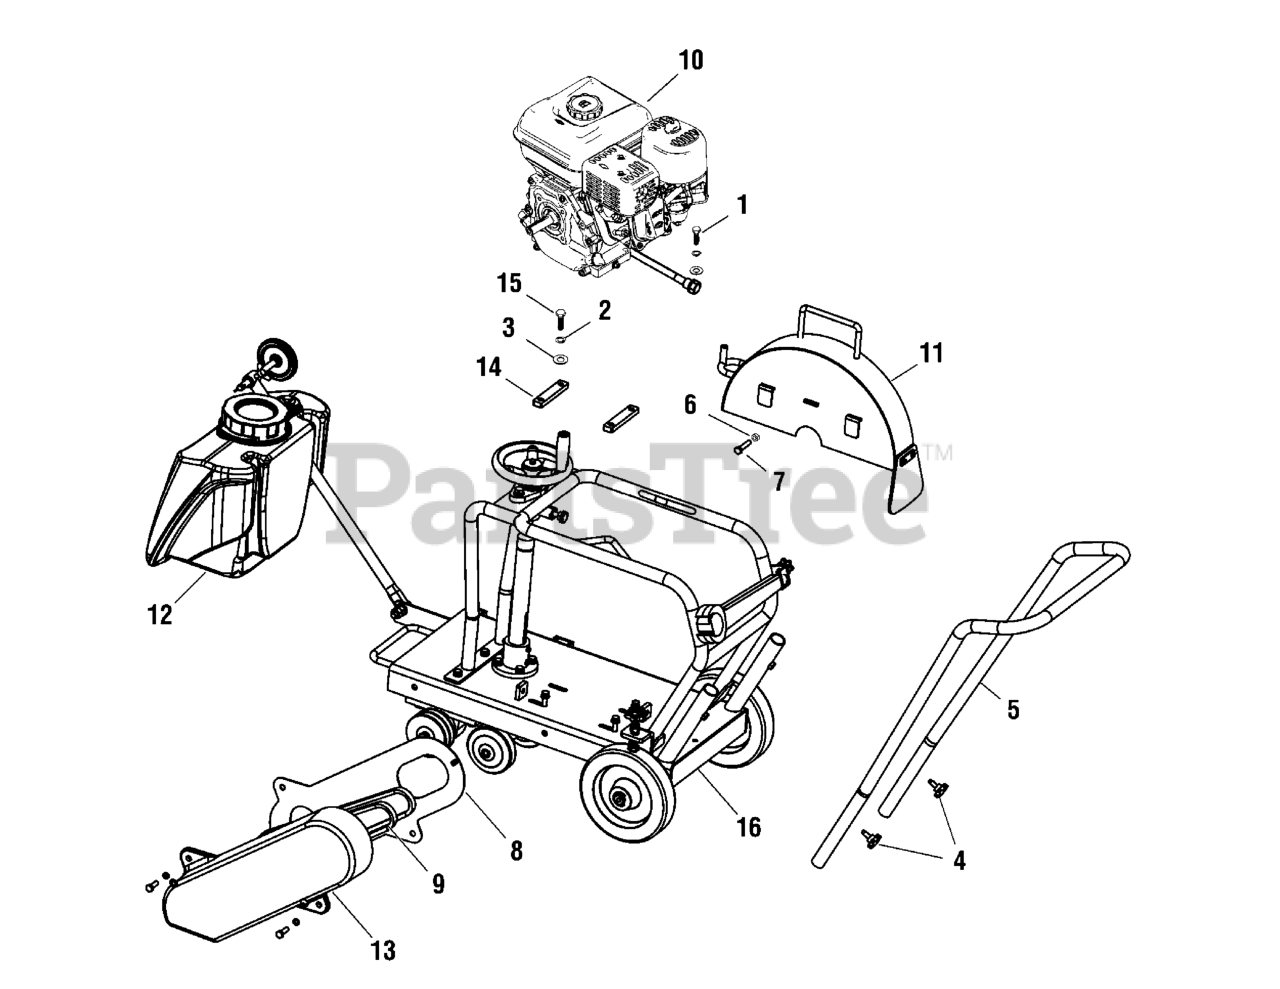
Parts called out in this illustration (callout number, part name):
1	BOLT, Hex, M8 x 25
2	WASHER, Spring, 8
3	WASHER, Flat, 8
4	KNOB, Bolt, M10
5	BOLT, Hex, M8 x 40
6	HANDLE
7	NUT, Hex, M8
8	COVER, Belt, Inner
9	BELT, XPA882
10	ENGINE ASSEMBLY
11	BLADE COVER ASSEMBLY
12	WATER TANK ASSEMBLY
13	COVER, Belt, Outer
14	PLATE, Engine Locking
15	BOLT, Hex, M8 x 50
16	WATER TANK FRAME ASSEMBLY
